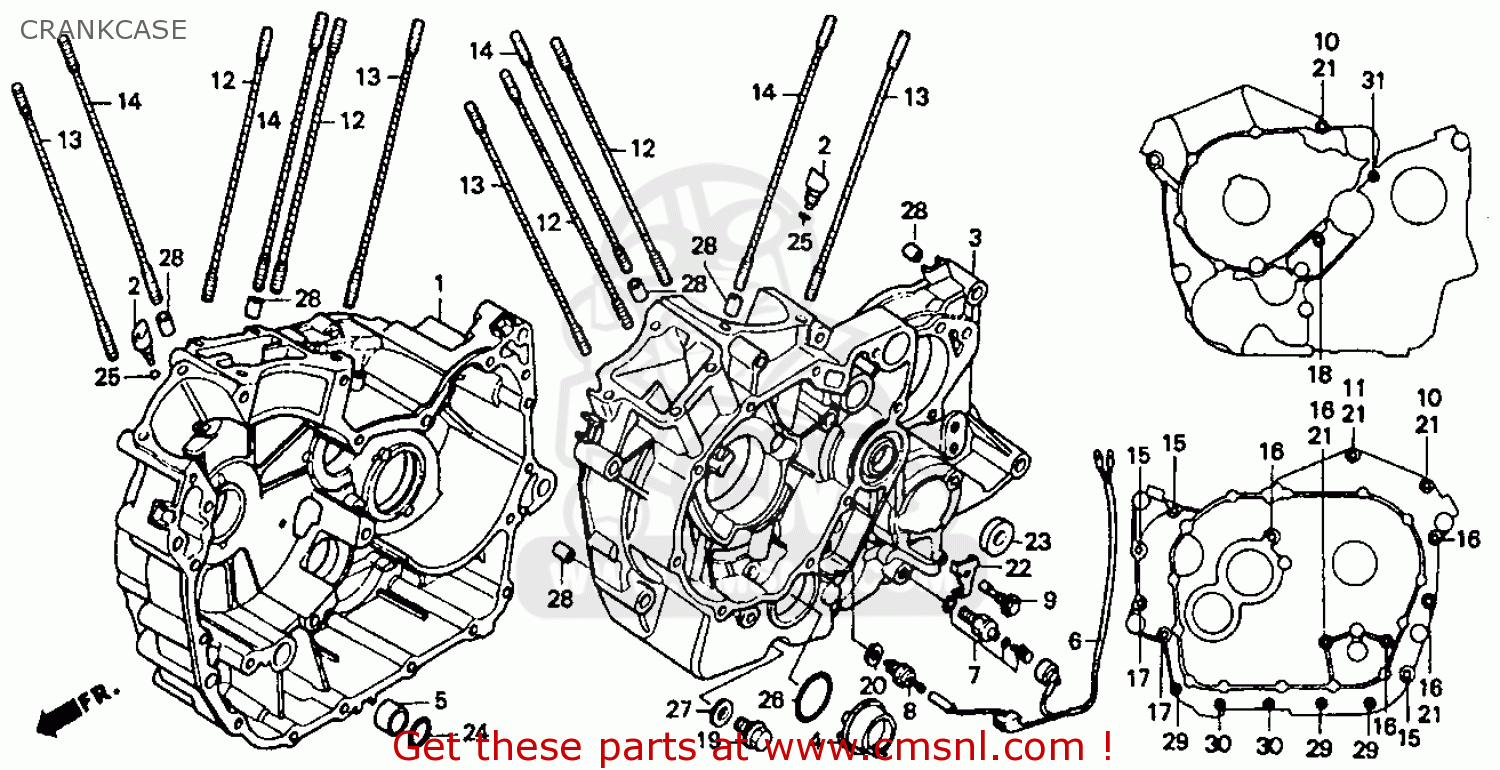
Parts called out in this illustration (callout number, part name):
1	CRANK CASE COMP.,
2	JET,OIL
3	CRANKCASE COMP.L.
4	PLUG,L.CRANKCASE
5	COLLAR,O RING
6	SUB HARNESS A
7	SW ASSY OIL PRESU
8	SW.ASSY,NEUTRAL
9	BOLT ORIFICSE 1.6
10	BOLT FRANGE,8X125
11	BOLT FRANGE,8X136
12	BOLT STUD 8X267
13	BOLT,STUD,10X269
14	BOLT,STUD,10X257
15	BOLT,FLANGE,8X45
16	BOLT,FLANGE,8X80
17	BOLT,FLANGE,8X100
18	BOLT,FLANGE SOCKE
19	BOLT,PLUG,14MM
20	WASHER,NEUTRAL SW
21	WASHER SEALING 8
22	PLATE,SEALING,6MM
23	OIL SEAL,8X25X7
24	O-RING,13.8X2.5
25	O-RING,5X1.7
26	O-RING,35.3X2.4
27	WASHER,PLUG DRAIN 14
28	DOWEL,PIN,14X20
29	BOLT,FLANGE 6X50
30	BOLT,FLANGE,6X90
31	BOLT,FLANGE,6X100
